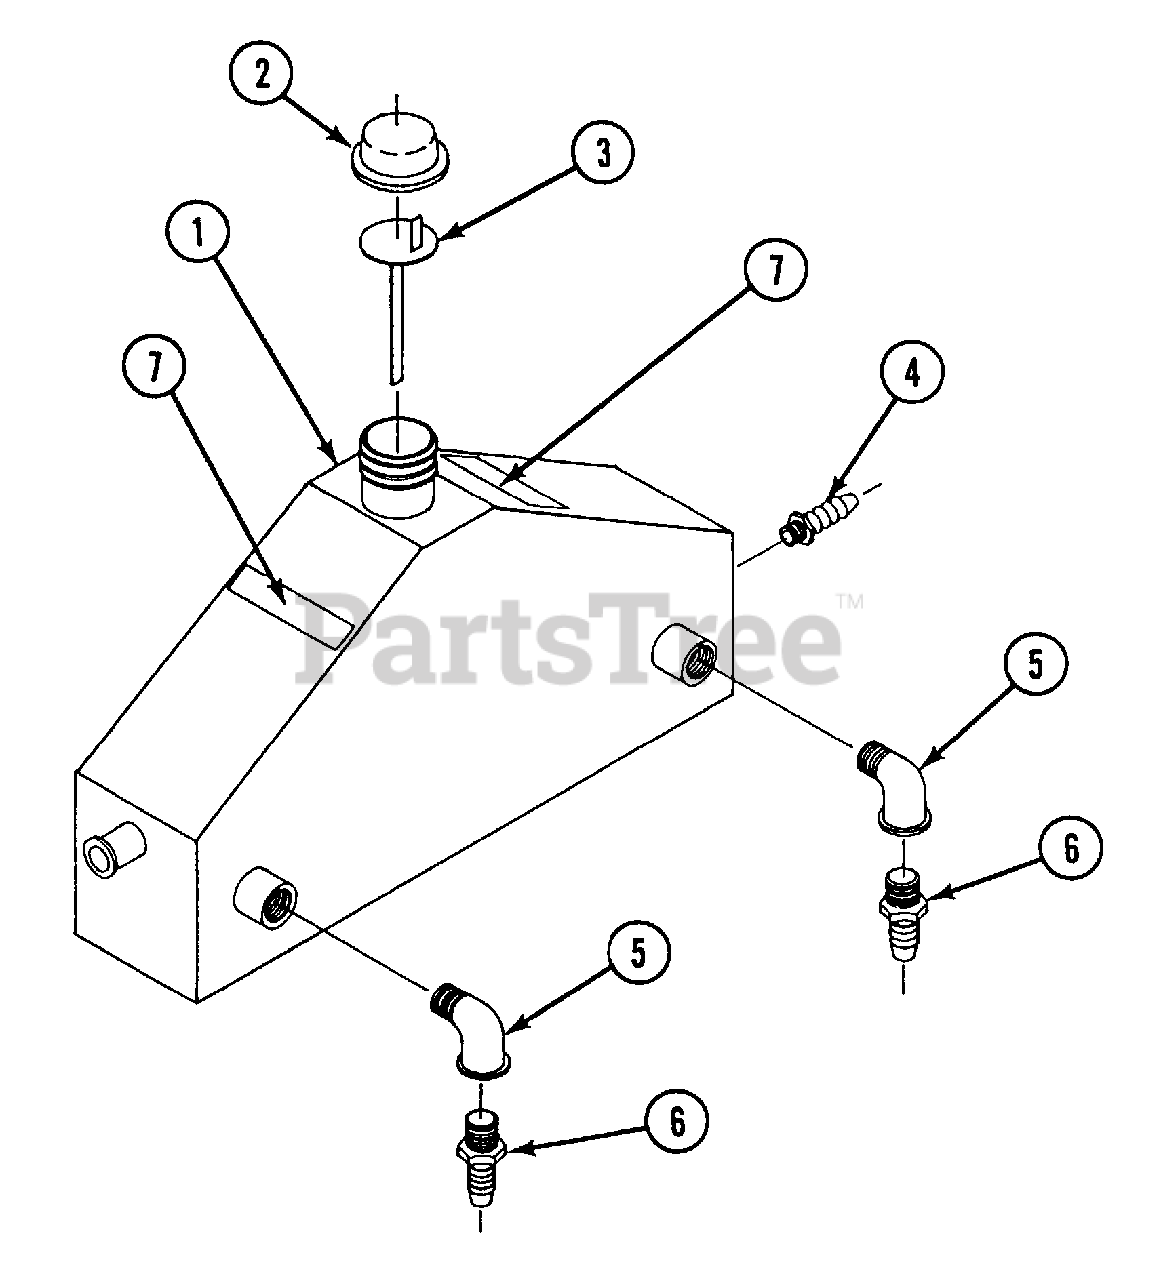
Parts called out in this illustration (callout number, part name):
1	OIL TANK WELDMENT
2	OIL TANK CAP
3	DIPSTICK WELDMENT
4	HOSE BARB, 1/4 HOSE X 1/4 NPTM
5	STREET EL, 1/2 BRASS
6	HOSE BARB, 3/4 HOSE X 1/2 NPTM
7	DECAL, "TRANSMISSION FLUID"
